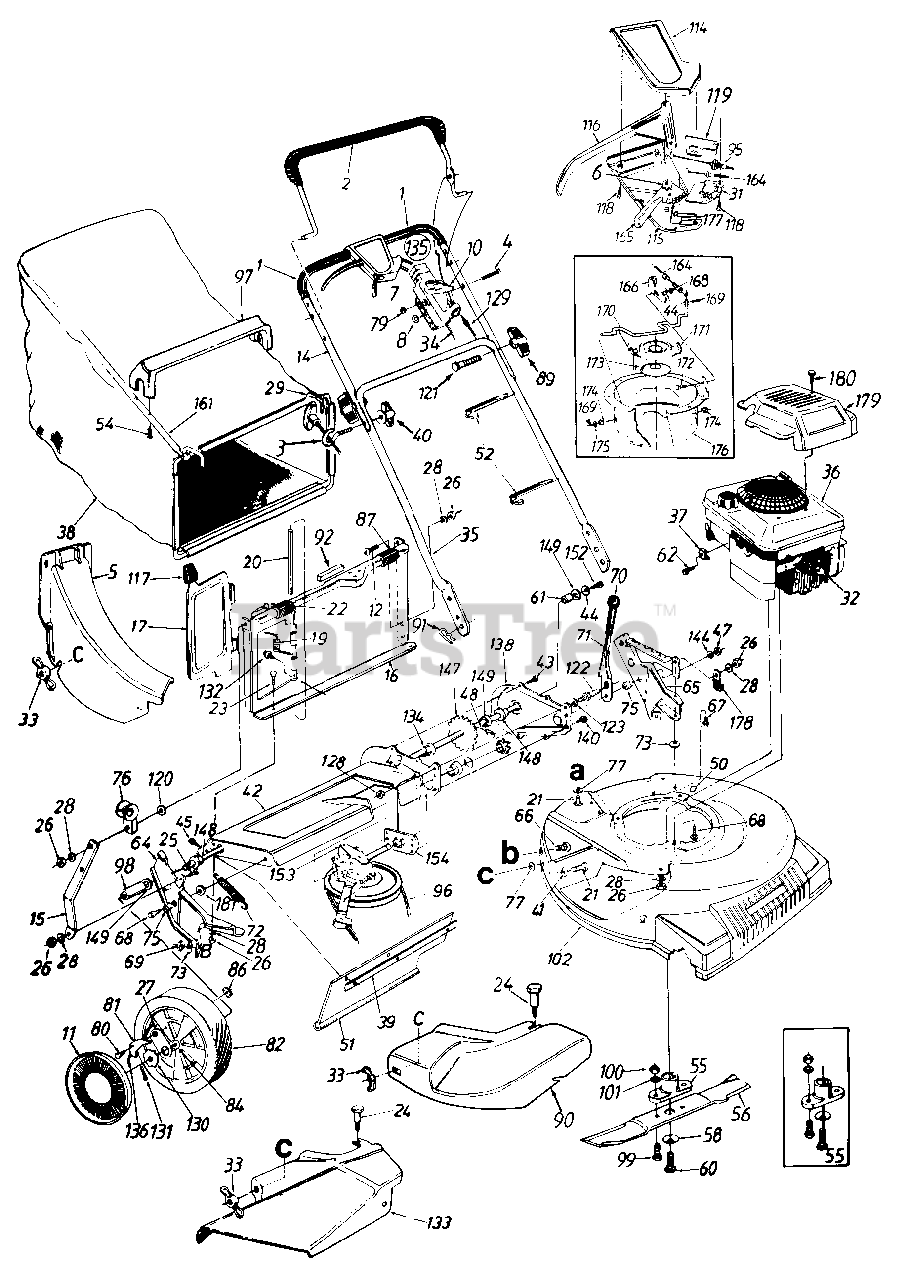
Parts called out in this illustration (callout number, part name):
1	Grip (2 Req'd.)
2	Control Handle
3	Rope Guide
4	Oval C-Sunk Scr.
5	Rear Discharge Chute Ass'y.
6	3 Tooth Rack Gear Insert
7	Throttle Body
8	Spr. Wash. .66" I.D.
10	Throttle Lever
11	Hub Cap (Beige)
12	Truss Mach. Scr. 1/4-20 x .62" Lg.
19	Torsion Spring
20	Pivot Pin
21	Carriage Bolt 1/4-20 x .62"
22	Truss Mach. Scr. 1/4-20 x .75" Lg.
23	Hex Bolt 1/4-20 x .5" Lg.
24	Shoulder Bolt Special
25	Hex Bolt 1/4-20 x .62" Lg.
26	Hex Nut 1/4-20 Thd.
27	Pawl Plate
28	L-Wash. 1/4" I.D.
31	S.P. Control Cover
32	Spark Plug Insulator
33	Wing Nut
34	Throttle Cable 61"
36	Engine
37	Casing Clamp
38	Grass Bag
39	Retaining Strip
40	Wing Nut 1/4-20 Thd.
41	Fl-Wash. .344" I.D. x .62"
44	Bell-Wash. 1/4" I.D.
45	Hex AB-Tap Scr. 1/4 x .62"
47	Hex Patch L-Nut 3/8-24 Thd.
48	#48 Chain .500" Pitch x 30 Links
51	Rear Flap 3.75" x 17.30" Lg.
52	Cable Tie
54	Hex AB-Tap Scr. #12 x 1.25" Lg.
55	Blade Adapter Kit
56	21" Mulching Blade
58	Bell-Wash. .46" I.D.
60	Hex Bolt 7/16-20 x 1.5"
61	Spacer.513" I.D.
62	Hex Wash. Hd. Scr. #10-32 x .62" Lg.
64	R.H. Handle Wheel Brkt. Ass'y.
65	L.H. Handle Wheel Brkt. Ass'y.
66	Carriage Bolt 5/16-18 x .62"
67	Hex B-Tap Scr. 5/16-18
68	Hex TT-Tap Scr. 3/8-16
69	Hex Nut 5/16-18 Thd.
71	Height Adj. Lever
72	Extension Spring 3.80" Lg.
73	Bell-Wash. 5/16" I.D.
75	Shld. Spacer .5" Dia.
76	Rope Guide
77	Bolt Retainer 1/4 x .50" O.D.
79	Hex L-Nut 1/4-20 Thd.
80	Shld. Scr. .342" Dia. x .268
81	Pawl
82	Wheel Ass'y. Comp. (Beige)
84	Sleeve Bearing 1/2" I.D.
86	Flat Nut 1/4-20 Thd.
87	Panel Clip
89	Hand Knob
90	Mulching Plug
91	Hairpin Clip
95	S.P. Cable--50" Lg.
96	"V"-Belt
97	Bag Handle
98	Sleeve .526" I.D.
99	Hex Bolt 3/8-24 x 1.0" Lg.
100	Hex Nut 3/8-24 Thd.
101	L-Wash. 3/8" I.D.
115	Self-Propelled Control Cover
116	Control Lever
117	Door Grip
118	Fl-"C"-Sunk Hd. Tap Scr. #10 x .75" Lg.
119	6-Speed Rack Cable Brkt.
120	Fl-Wash. .285" I.D. x 1.25" O.D.
121	Curved Hd. Bolt 5/16-18 x 2" Lg.
122	Shld. Pin 1.43" Lg.
123	L-Wash. 3/8" I.D.
128	Hex Jam Nut 3/8-24 Thd.
129	Control Cable--44"
130	Ratchet Wheel 1.62" O.D.
131	Cotter Pin 1/8" Dia. x 1"
132	Hex B-Tap Scr. #10 x .38" Lg.
133	Side Chute Deflector Ass'y.
134	Hex Flange Bearing
135	Throttle Box Comp.
136	Spring--Nylon
144	Fl-Wash. .385" I.D. x .87"
147	Rear Shaft Ass'y. 21.94" Lg.
148	Hex Flange Brg. .506" I.D.
149	Fl-Wash. .531" I.D. x .930"
152	Hex Bolt 1/4-20 x .62" Lg. (Grade 5)
153	Transmission Comp.
164	Spd. Control Cable--50" Lg.
165	6-Spd. Shift Lever
169	Cot-Pin 3/32" Dia. x .75" Lg.
170	Shift Rod
171	Movable Pulley Half Ass'y
172	Carr. Bolt 1/4-20 x .5" Lg.
173	Splined Pulley Half
174	Flanged Bushing
175	Fl-Wash. .328" I.D. x .68" O.D.
176	Housing Ass'y.
177	Shift Lever Spring
179	Engine Cover (Black)
180	Screw #10 x 1.25" Lg.
181	Fl-Wash. .383" I.D. x 1" O.D.
